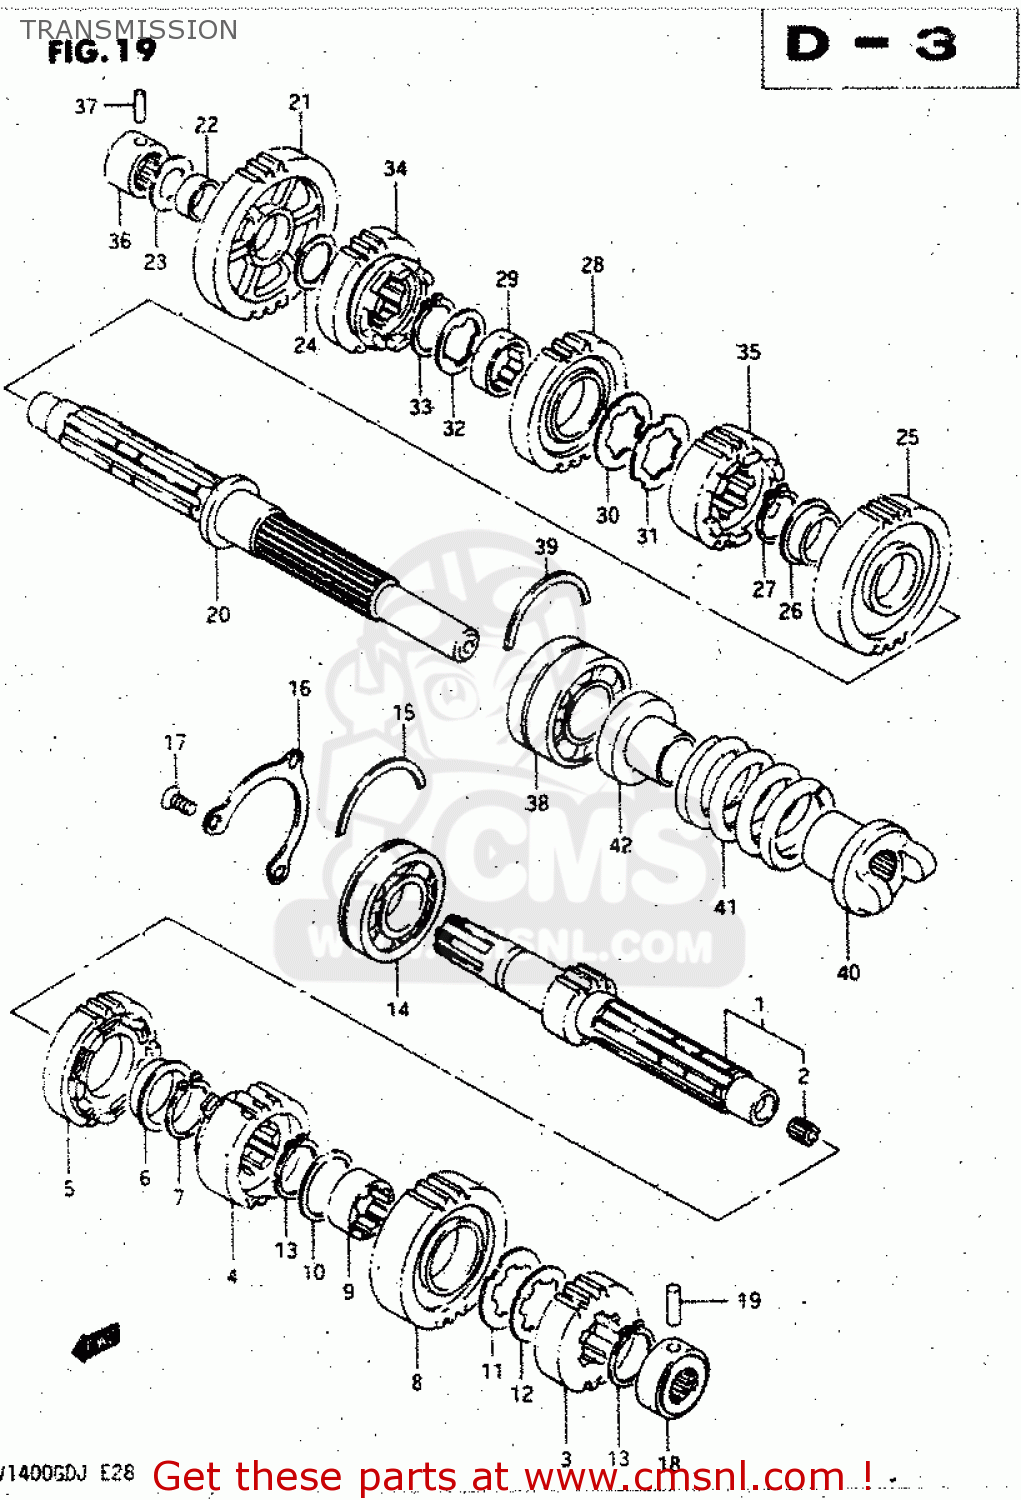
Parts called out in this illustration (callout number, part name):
1	SHAFT,COUNTER
2	BUSH
3	GEAR,SECOND DRIVE
4	GEAR,THIRD DRIVE
5	GEAR,FOURTH DRIVE
6	BUSH(28X32X2)
7	CIRCLIP
8	GEAR,FIFTH DRIVE
9	BUSH
10	WASHER,LOCK
11	WASHER,LOCK
12	WASHER,LOCK
13	CIRCLIP
14	BEARING(25X62X17)
15	C-RING
16	PLATE,COUNTERSHAFT BEARING
17	SCREW
18	ROLLER BEARING (20X36X1
19	PIN
20	SHAFT,DRIVE
21	GEAR,FIRST DRIVEN
22	BUSHING
23	WASHER
24	WASHER
25	GEAR,SECOND DRIVEN
26	BUSH(28X32X2)
27	CIRCLIP
28	GEAR,THIRD DRIVEN
29	BUSH,3RD DRIVEN GEAR
30	WASHER
31	WASHER,LOCK
32	WASHER,LOCK
33	CIRCLIP
34	GEAR,FOURTH DRIVEN
35	GEAR,FIFTH DRIVEN
36	BEARING(20X34X20)
37	PIN
38	BALL BEARING 30X62X28
39	C-RING
40	DOG,INPUT CAM
41	SPRING
42	STOPPER,CAM SPRING
